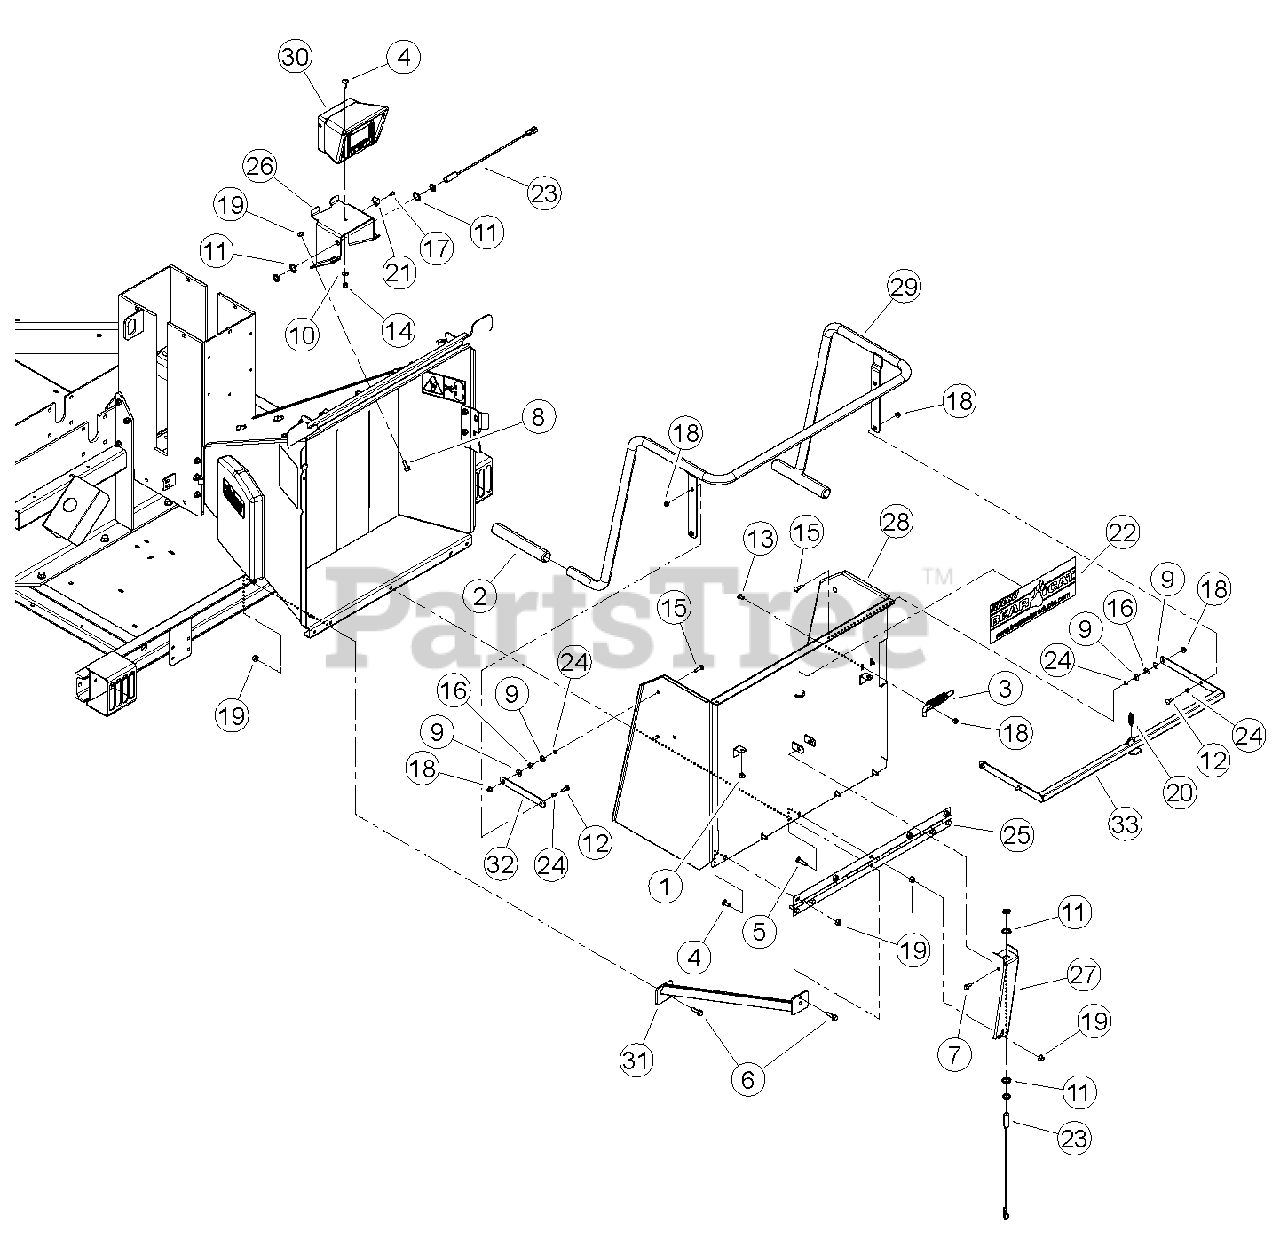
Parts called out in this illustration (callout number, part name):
1	BUMPER, RUBBER
2	GRIP, 1.219 X 10.00
3	LATCH, RH HINGE
4	BOLT, 3/8 X 1" GR5 CRG NC ZP
5	BOLT, 3/8 X 1-1/2" GR5 CRG NC ZP
6	BOLT, 3/8 X 1-1/4 FLANGE NC
7	BOLT, 5/16 X 3/4 FLANGE NC
8	BOLT, 3/8 X 1 FLANGE NC
9	WASHER, 5/16" FLAT ZP
10	WASHER, 3/8" SAE FLAT ZP
11	WASHER, 3/4 INTERNAL LOCK
12	BOLT, 5/16 X 1" GR5 CRG ZP
13	BOLT, 5/16 X 3/4 GR5 CRG NC ZP
14	NUT, 3/8" NE NYLOCK ZP
15	BOLT, 5/16 X 1-1/4" GR5 CRG ZP
16	WASHER, 5/16" ID 7/8" OD NYLON FLAT
17	RIVET, AL BLIND 1/4 X 3/4 DOME HEAD
18	NUT, 5/16-18 NYLOCK-FLANGE
19	NUT, 3/8-16 NYLOCK FLANGE
20	SPRING, 1/2 X 2.00 LG ZP
21	CLAMP, CABLE MOUNT
22	DECAL, BEARCAT WEB
23	SENSOR, M18 PROXIMITY (REPLACEMENT PART)
24	SPACER, IDLER PIVOT
25	HINGE, EXTENSION TRAY
26	MOUNT, 5/8/9" DDC
27	MOUNT, 5/8/9" KNEEBAR PROX SENSOR
28	WELDMENT, INFEED TRAY
29	WELDMENT, 9" TOWABLE KNEE BAR
30	ASSEMBLY, DDC ENCLOSURE
31	WELDMENT, CHUTE SUPPORT
32	LINK, PARALLEL
33	WELDMENT, KNEEBAR PIVOT
